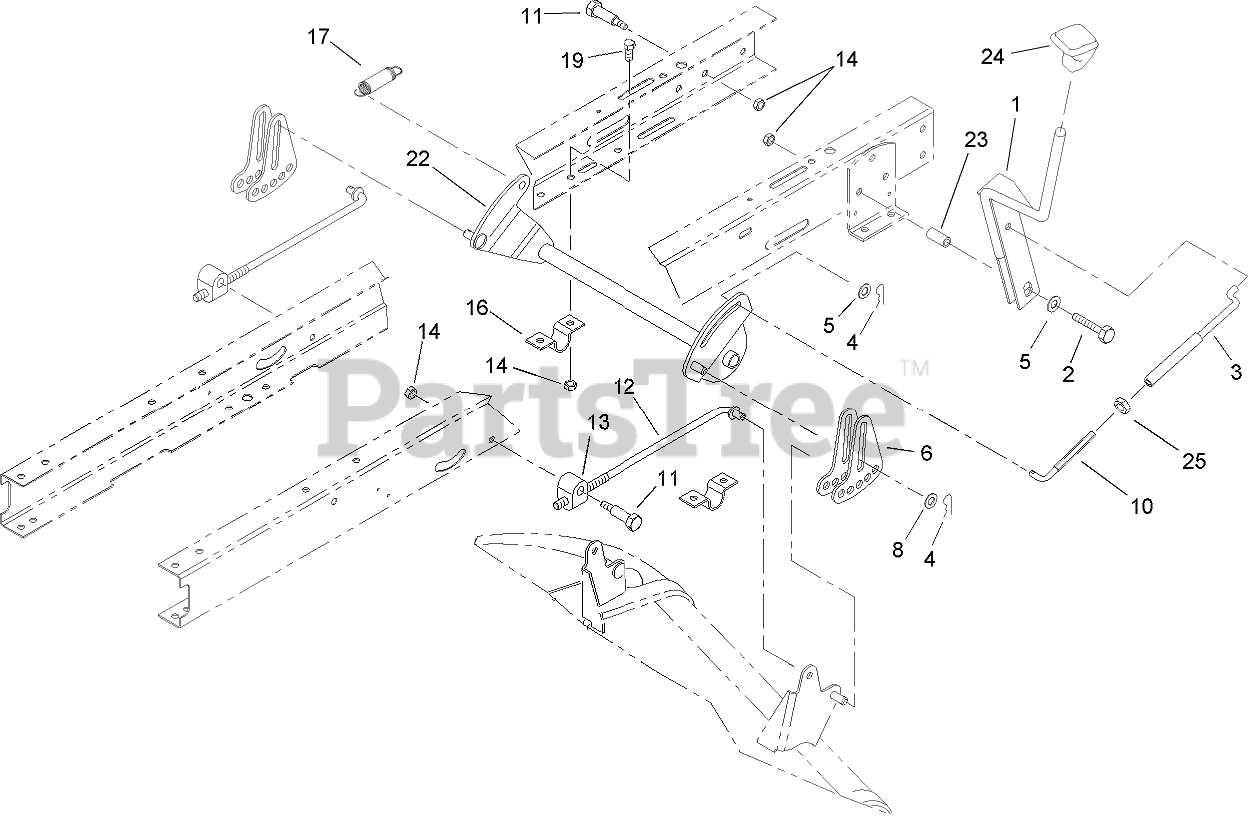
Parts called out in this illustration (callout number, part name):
1	HOC LEVER ASM
2	SCREW-HH
4	PIN-COTTER
5	WASHER-FLAT
6	LINK-ADJUSTING, HOC
8	WASHER-HARDENED
10	LINK-HOC
11	SCREW-SHOULDER, HH
12	ROD-HANGER, REAR
13	TRUNNION-HOC
14	NUT-LOCK, NI
16	CLAMP-PIVOT, HOC
17	SPRING-EXTENSION
19	SCREW-HH
22	PIVOT-HOC
23	SPACER
24	KNOB-SHIFT
25	NUT-JAM
